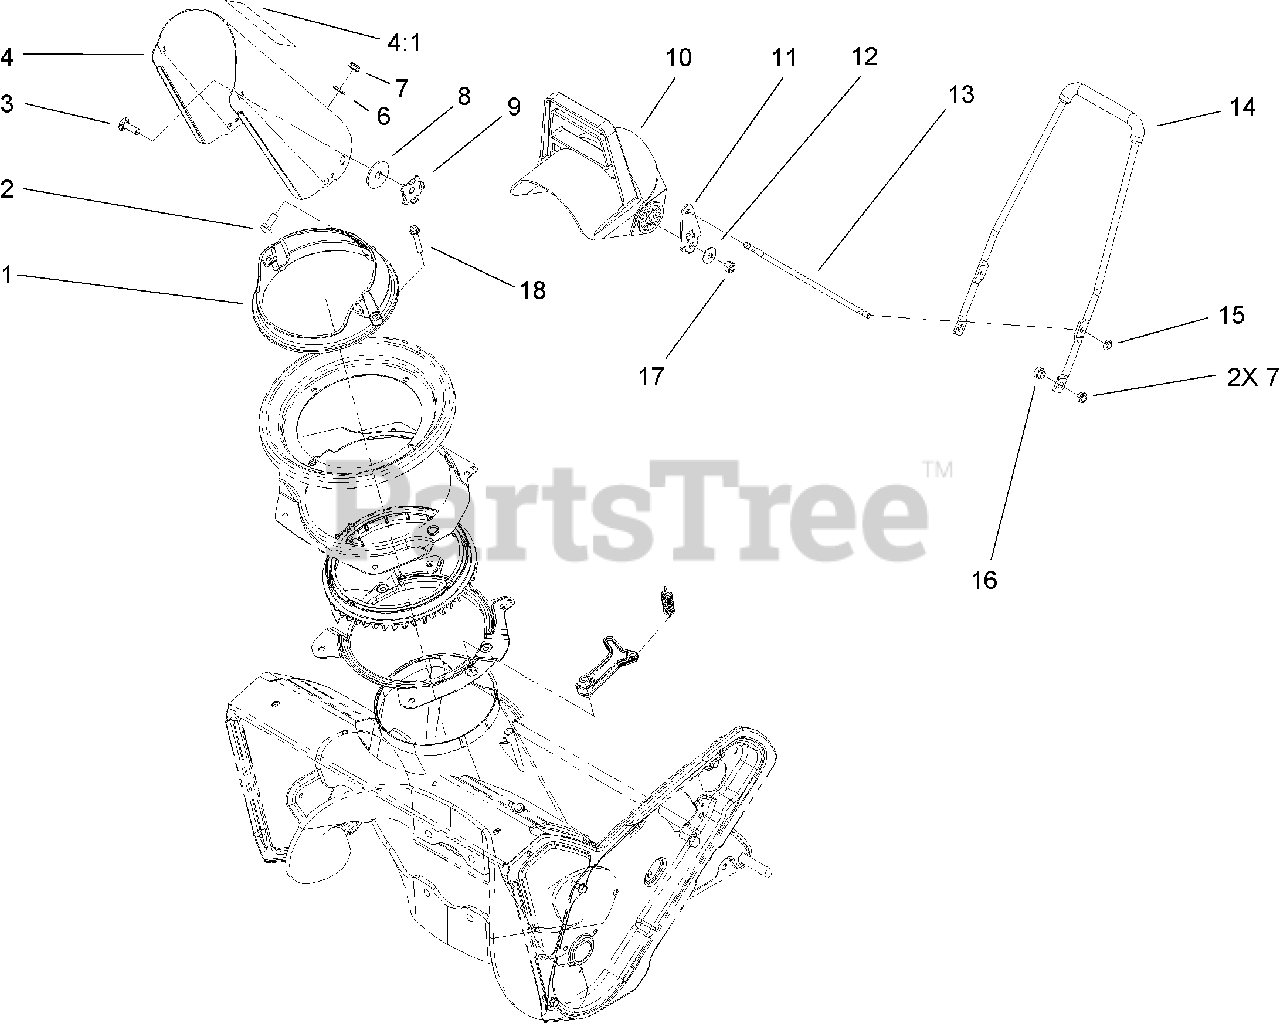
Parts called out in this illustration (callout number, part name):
1	RING-CHUTE
2	SCREW-CARR
3	SCREW-CARR
4	CHUTE ASM
4:1	DECAL-DANGER
6	WASHER-FLAT
7	NUT-LOCK, NI
8	WASHER-RUBBER
9	PLATE-FRICTION
10	CHUTE-DEFLECTOR
11	CHUTE-PIVOT ARM
12	WASHER-BELLEVILLE
13	LINKAGE-CHUTE
14	HANDLE-FOAM
15	RETAINER-PUSH ON
16	SPACER-FLANGED
17	NUT-LOCK, NI
18	SCREW-PLASTITE
